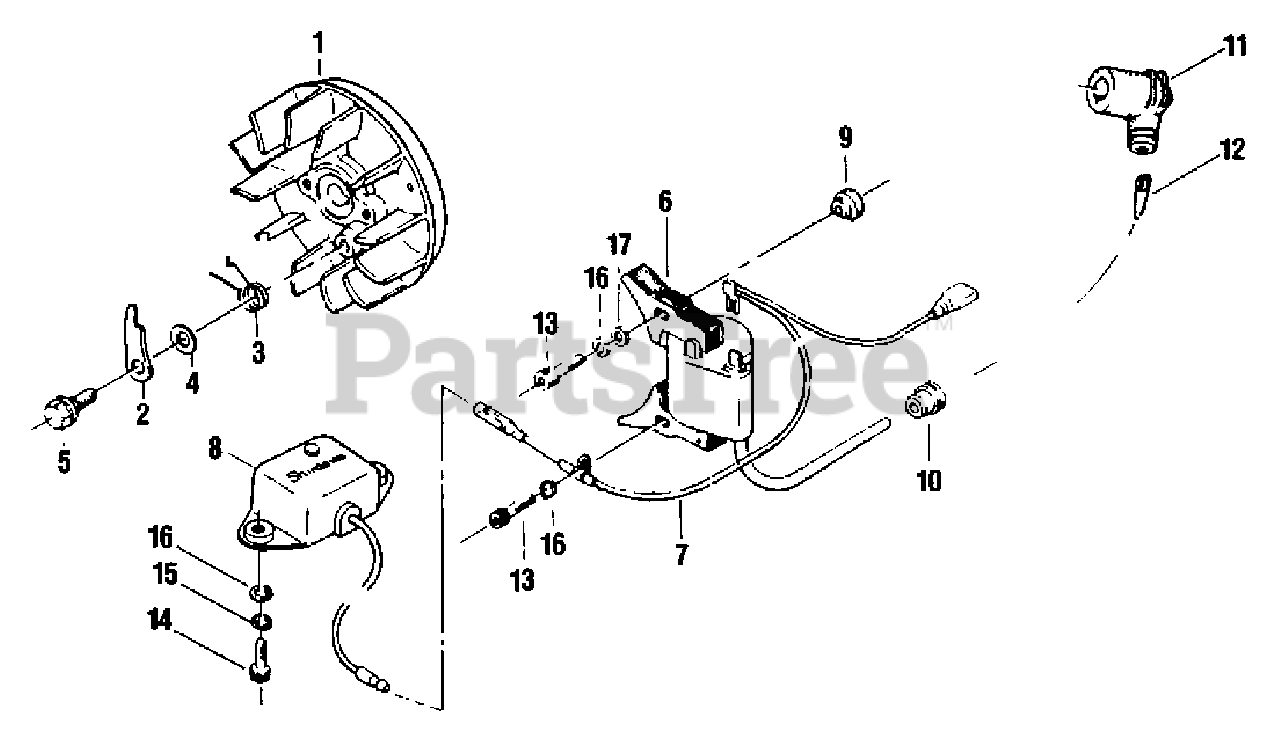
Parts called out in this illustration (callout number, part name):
1	ROTOR
2	PAWL, STARTER
3	SPRING, RETURN
4	WASHER - 6
5	BOLT
6	COIL
8	UNIT
11	CAP, SPARK PLUG
12	TERMINAL, SPARK PLUG CAP
13	SCREW - 4X24
14	SCREW - 4X10
15	LOCKWASHER - 4
16	WASHER - 4
